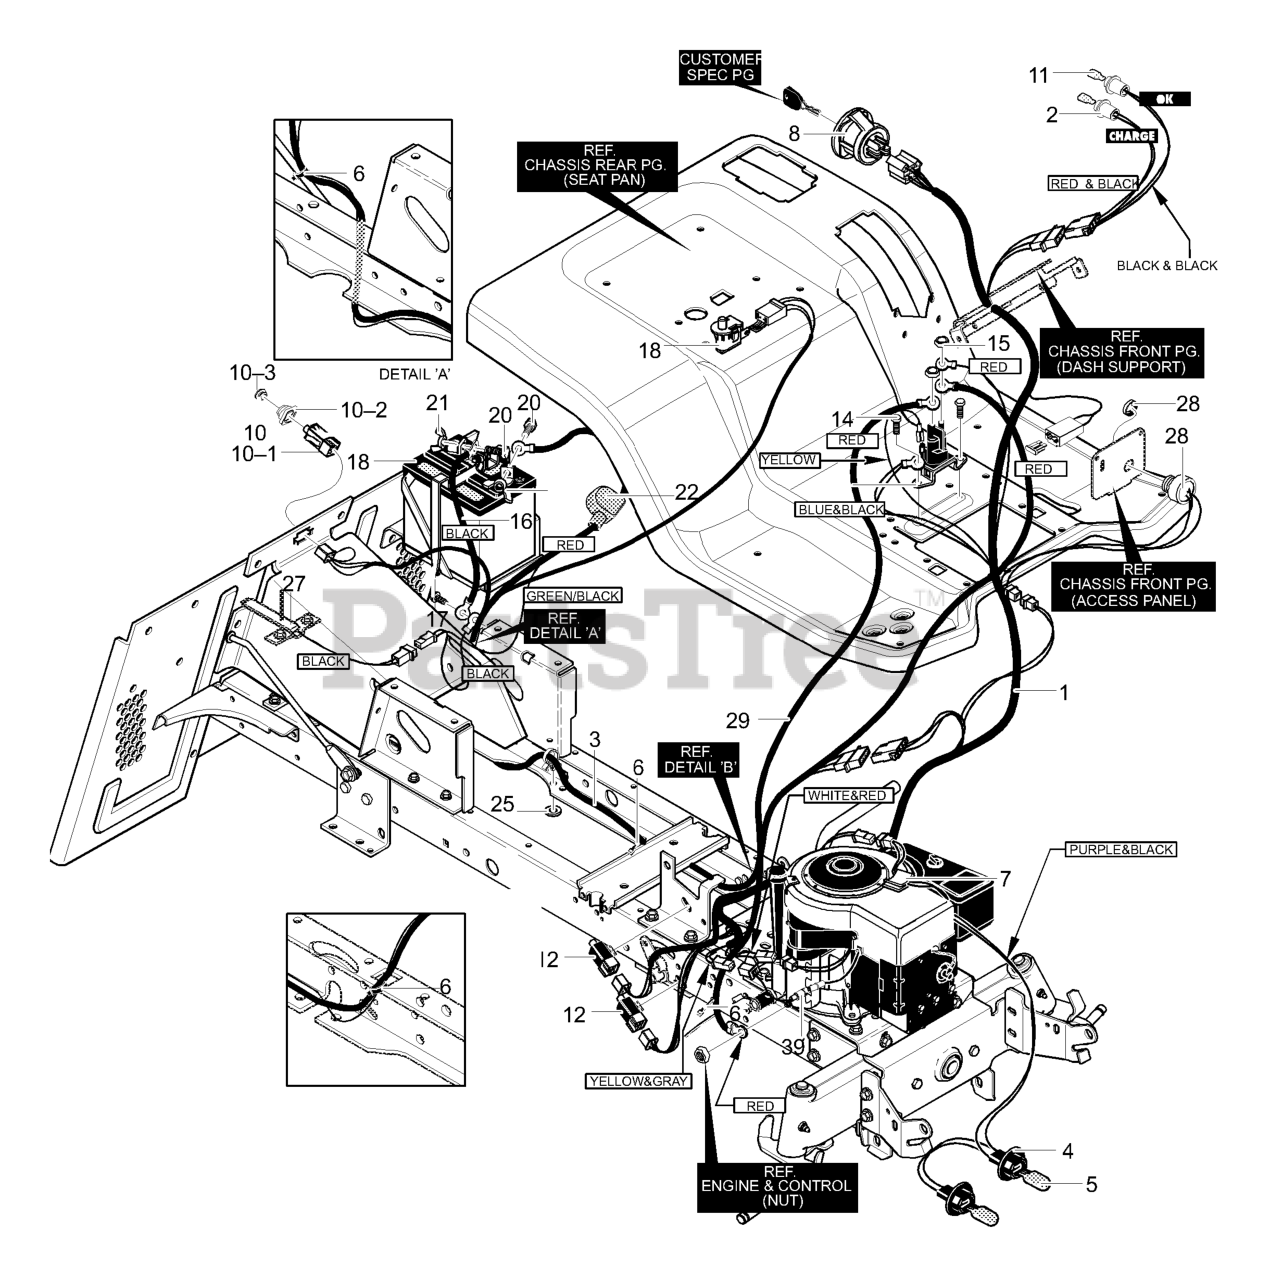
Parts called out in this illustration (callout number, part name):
1	Wire Harness
2	Indicator Harness
3	Rear Harness
4	Wire Harness for Headlights
5	Bulb, Headlamp
6	Cable Tie
7	Wire Clip, Adhesive
8	Switch, Ignition
10	Assy, Switch Double Pole Delta
10-1	Switch, Double
10-2	Boot, Switch
10-3	Switch Cap
11	Bulb, Indicator
12	Switch, Limit
13	Solenoid
14	Screw 1/4x.50
15	Nut, 1/4-20
16	Ground Wire
17	Screw, 1/4x.50
18	Seat Switch
19	Battery 5 Plate
20	Bolt, 1/4-20x.63
21	Wing Nut
22	Battery Boot
25	Flatwasher
27	Tape Switch
28	Buzzer, For Bag Full
29	Wire, Lead Solenoid to Starter
39	Harness Adapter
